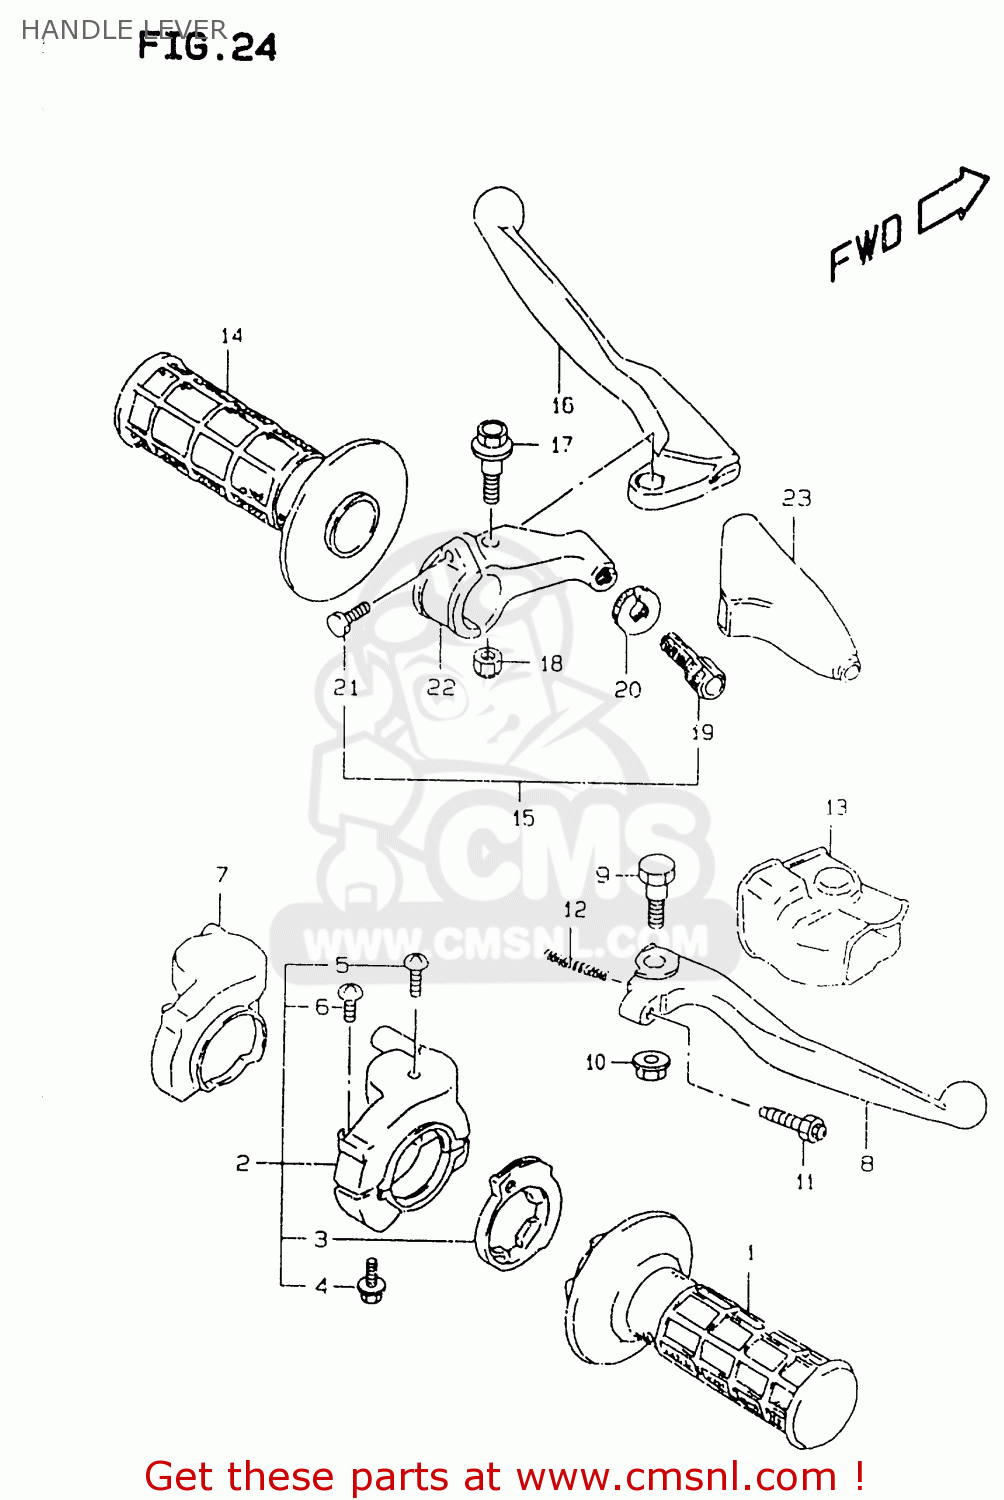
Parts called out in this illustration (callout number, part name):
1	GRIP,THROTTLE
2	CASE ASSY,THROTTLE
3	ROTOR,THROTTLE
4	BOLT 6X25
5	SCREW,UPPER
6	SCREW
7	COVER,THROTTLE CASE
8	LEVER,BRAKE
9	BOLT,BRAKE LEVER
10	NUT,BRAKE LEVER
11	BOLT,ADJUSTER
12	SPRING,RETURN
13	COVER,BRAKE LEVER
14	GRIP,L
15	LEVER ASSEMBLY,CLUTCH
16	LEVER,CLUTCH
17	BOLT,LEVER
18	NUT 6MM
19	ADJUSTER,WIRE
20	NUT,LOCK
21	BOLT
22	BRACKET,LEVER HOLDER
23	COVER,CLUTCH LEVER
